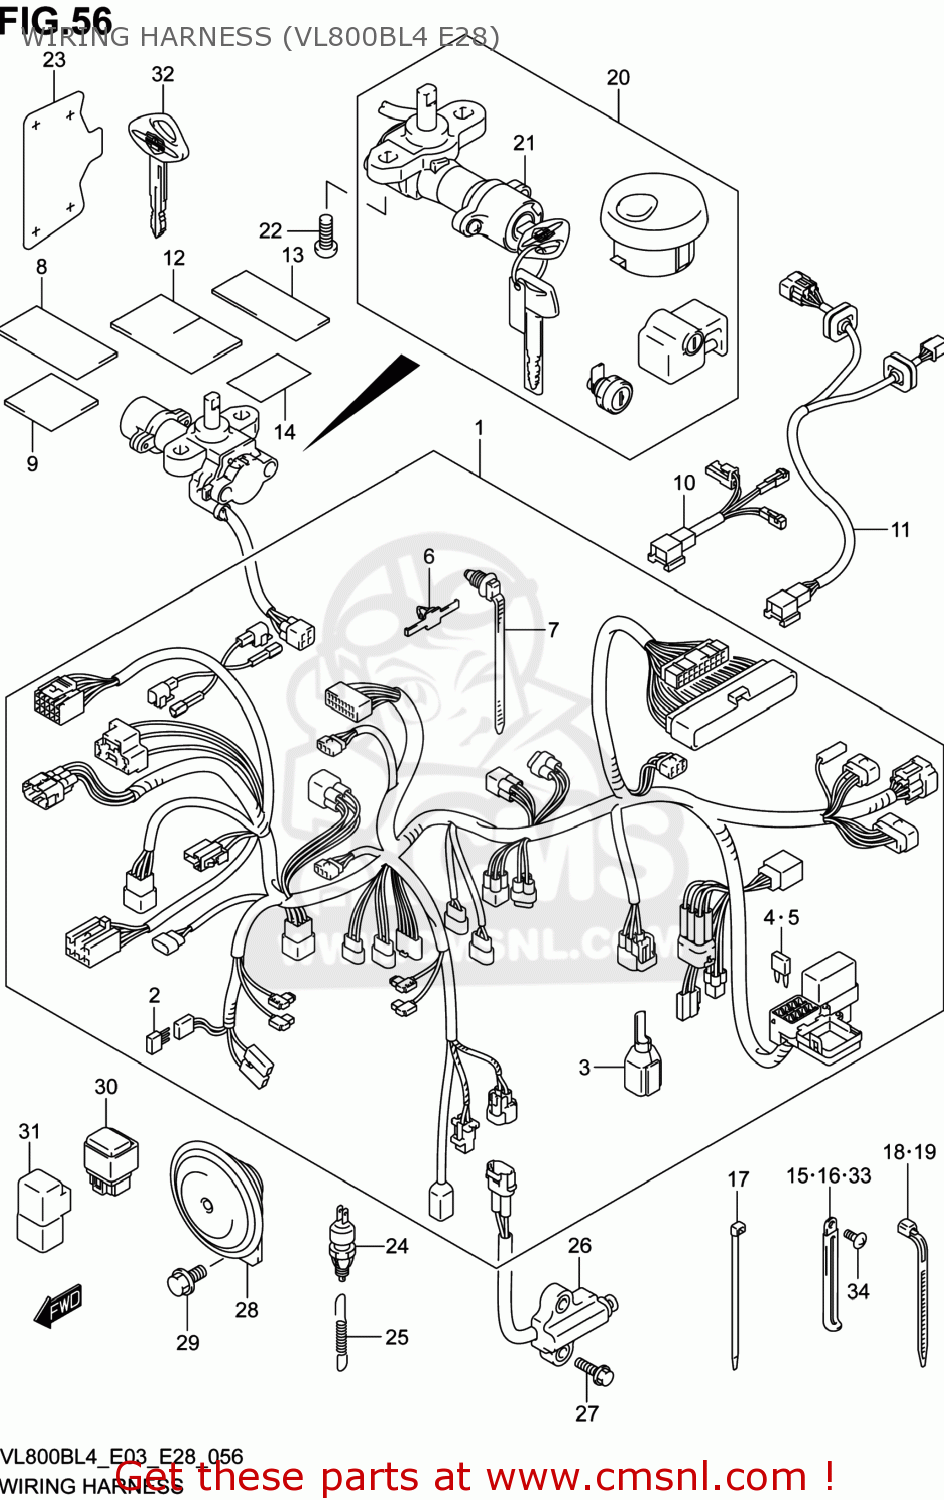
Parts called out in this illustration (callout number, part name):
1	HARNSSS, WIRING
2	RECTIFIER ASSY
3	BOOT
4	FUSE(10A)
5	FUSE(20A)
6	CLAMP
7	CLAMP(L:154)
8	TAPE,WIRING HARNESS(28X50X0.13
9	PROTECTOR,WIRING HARNESS
10	WIRE,RR COMB NO.2
11	WIRE,RR COMB
12	PROTECTOR,HARNESS(30X50X3)
13	PROTECTOR,WIRING HARNESS
14	PROTECTOR,COWLING UNDER
15	CLAMP(L:80)
16	CLAMP(L:135)
17	CLAMP(L:145)
18	CLAMP(L:165)
19	CLAMP(L:190)
20	LOCK SET
21	LOCK ASSY,STEERING
22	BOLT(8X20)
23	PROTECTOR,IGNITION SWITCH
24	SWITCH ASSY,STOP LAMP
25	SPRING
26	SWITCH ASSY,SIDE STAND
27	BOLT(6X20)
28	HORN ASSY
29	BOLT
30	RELAY ASSY
31	RELAY ASSY
32	KEY,BLANK(BOULEVARD)
33	CLAMP(L:45)
34	SCREW
